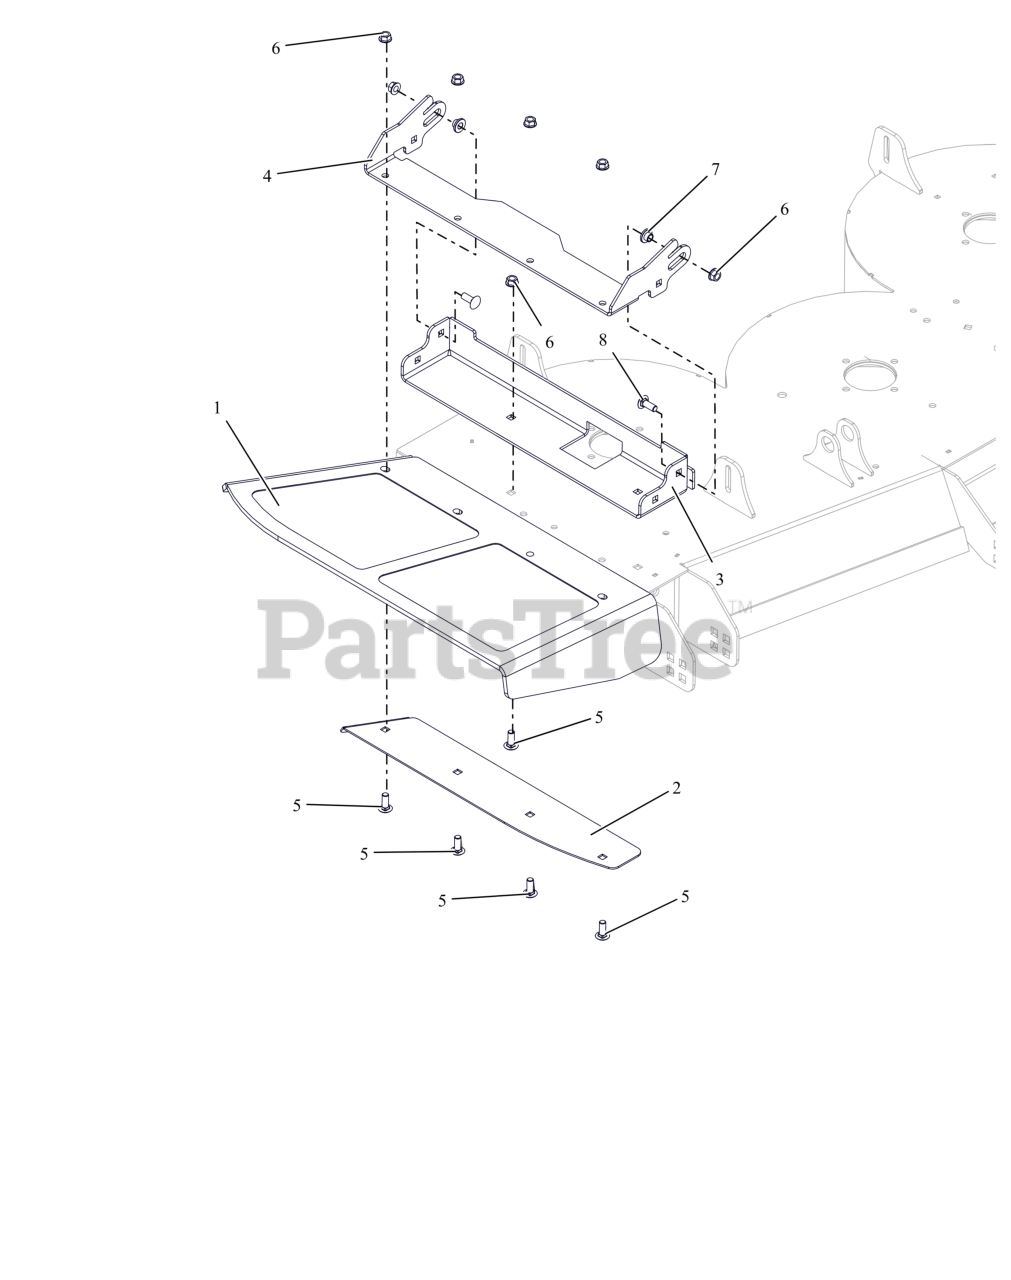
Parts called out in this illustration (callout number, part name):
1	CHUTE, 72" FORMED RUBBER DISCH
2	72" DISCH CHUTE CLAMP PLT-BLK
3	BASE, DISCHARGE CHUTE MTG (RED) W/ SAFETY DECALS
4	BRKT, CHUTE MTG (RED)
5	BLT,RHSSN .38-16X1.00 G5 ZCC
6	NUT-LK-CTR-FLG .375-16 GF ZCC
7	BSHG-FLG .385X.500X.875X.406
8	BLT,RHSSN .38-16X1.00 G5 ZCC
